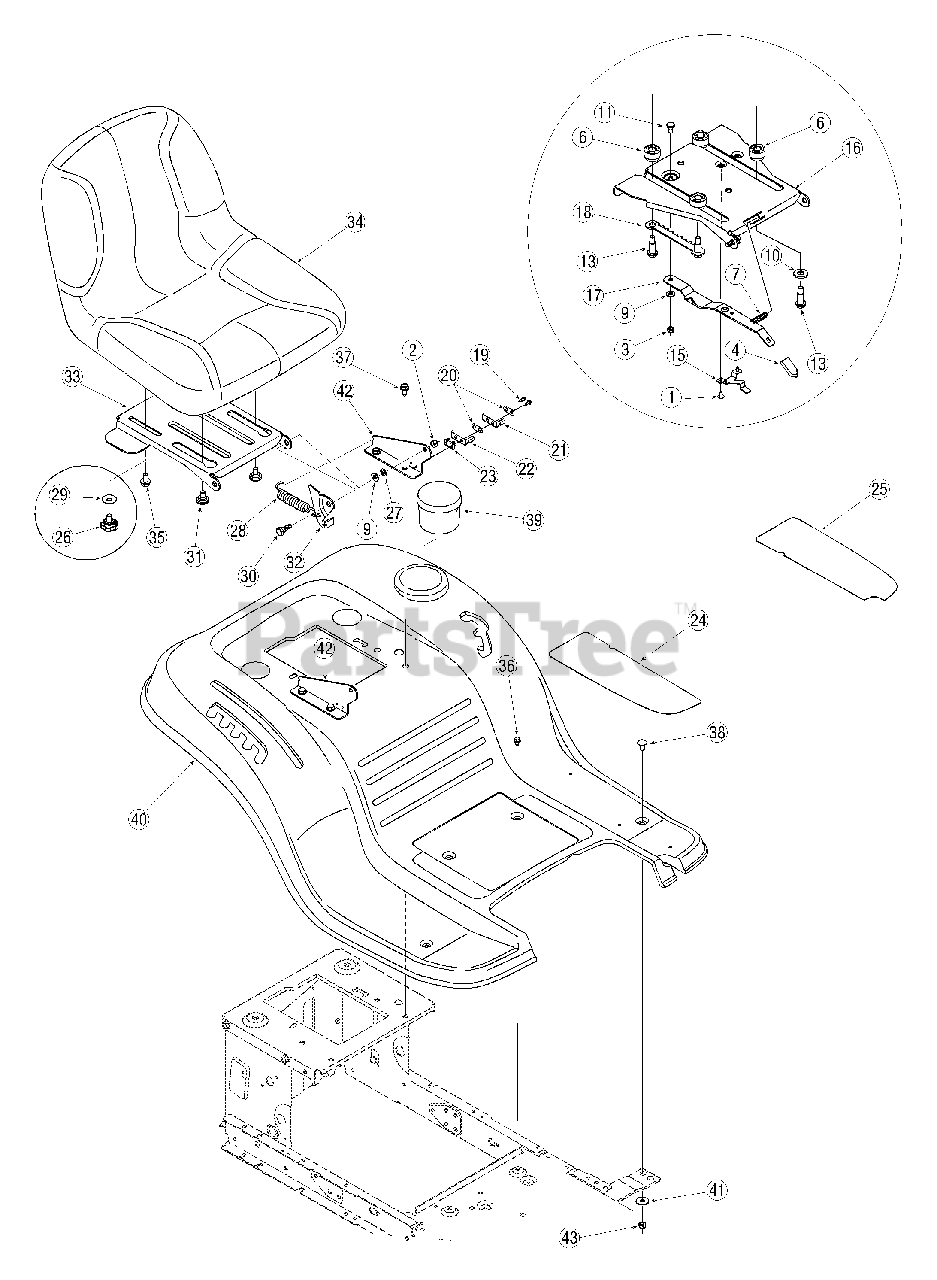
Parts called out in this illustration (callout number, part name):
1	Screw, #10-16, .375
2	Nut, Flange Lock, 5/16-18, Gr F, Nylon
3	Nut, Flange Lock, 1/4-20
4	Seat Adjuster Grip
5	Nut, Speed, .3125 ID
6	Spacer
7	Compression Spring, .41 x 1.5
8	Spring, Extension, .84 Dia. x 4.6
9	Wash, Flat, .344 x .688 x .065
10	Wash, Flat, .531x 1.062 x.134
11	Screw, Shoulder, .340 x .285,1/4-20
12	Screw, Shoulder, .437 x .268, 5/16-18
13	Screw, Shoulder, .50 x .925, 3/8-16
14	Seat Bracket, Lift
15	Seat Stop
18	Seat Adjustment Selector
19	Screw, #8-18 x .50
20	Plate, Insulator
21	Spring Switch, Inner
22	Spring Switch, Outer
23	Plate, Insulator Boss
24	Foot Pad, Abrasive, RH
25	Foot Pad, Abrasive, LH
26	Knob, 3/8-16, .625
27	Nut, Speed, .3125 Id
28	Spring, Extension, .84 Dia x 4.6 Lg.
29	Washer, Flat, .406 x 1.00 x .030
30	Screw, Shoulder, .437 x .268, 5/16-18
31	Screw, Shoulder, .625 x .175, 3/8-16
32	Lift Bracket, Seat
34	Seat, Low Back
35	Screw, 3/8-16, .625
36	Screw, 1/4-20, 0.500
37	Screw, 5/16-12, 0.750
38	Screw, Carriage, 1/4-20, .62 Gr2
39	Cup Holder
41	Washer, Flat, .28 x .74 x .063
43	Nut, Flange Lock, 1/4-20, Gr F, Nylon
